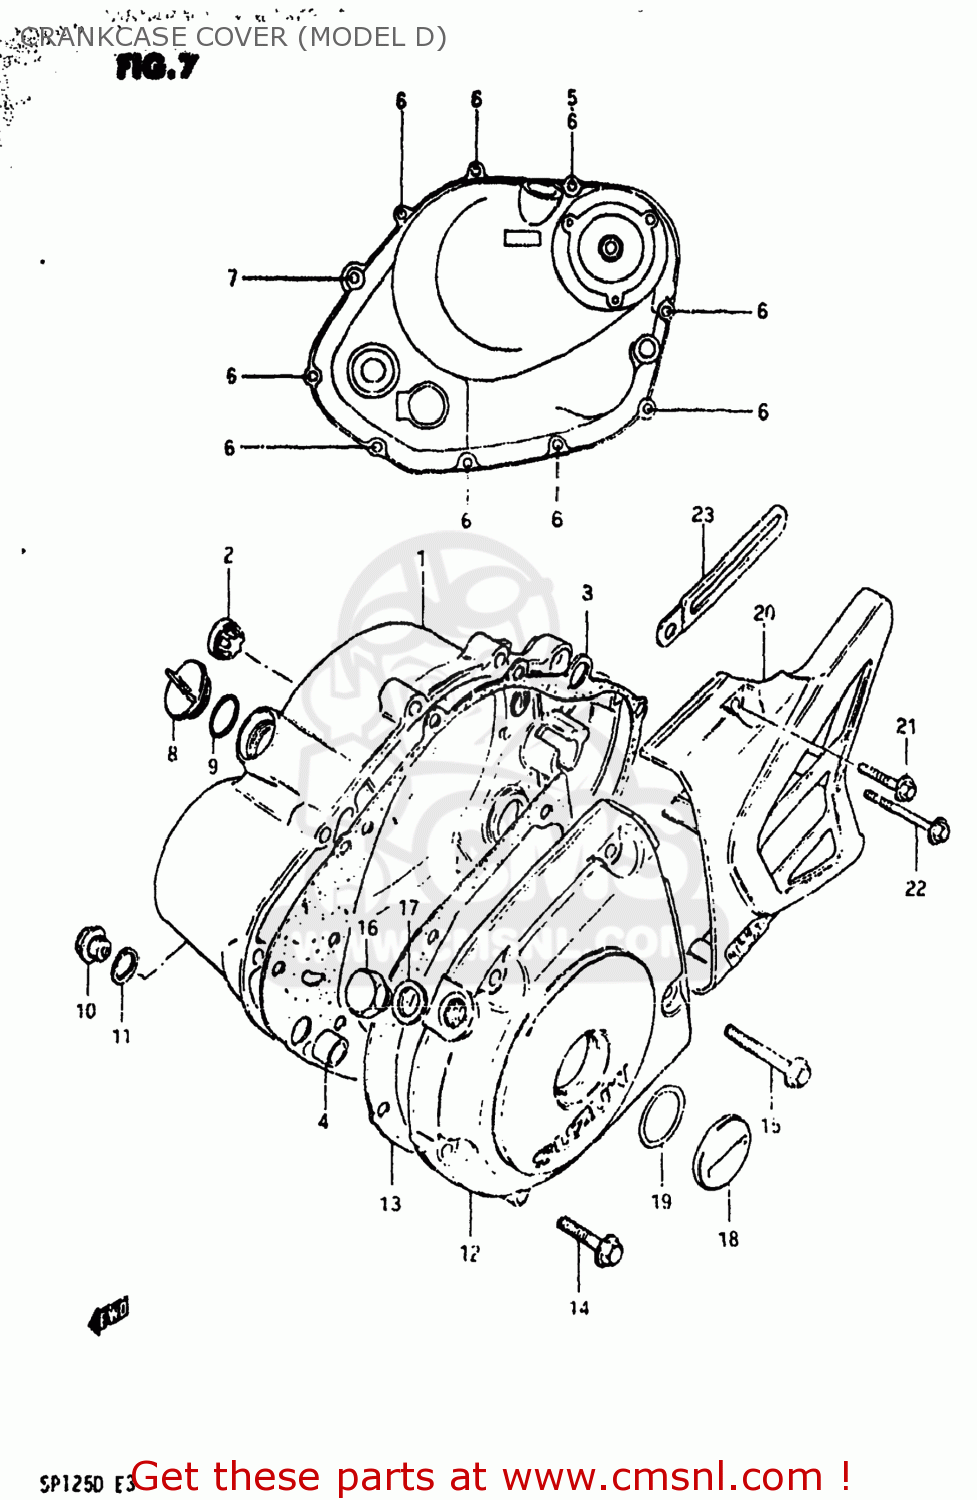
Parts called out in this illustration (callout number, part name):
1	COVER,CLUTCH
2	LENS,OIL LEVEL CHECK
3	GASKET,CLUTCH COVER (MCA)
4	PIN
5	GASKET (NAS)
6	BOLT (6*30)
7	BOLT (6X45)
8	PLUG
9	O RING(D:3.1,ID:16.8)
10	PLUG (14X12)
11	GASKET(14X19.2X2) (NAS)
12	COVER,MAGNETO
13	GASKET,MAGNETO COVER (MCA)
14	BOLT (6*30)
15	BOLT (6X40)
16	PLUG(12X9)
17	GASKET(12.1X16.2X3.7) (NAS)
18	PLUG
19	O RING(D:3.1,ID:22.7)
20	COVER,SPROCKET
21	BOLT
22	BOLT
23	CLAMP
